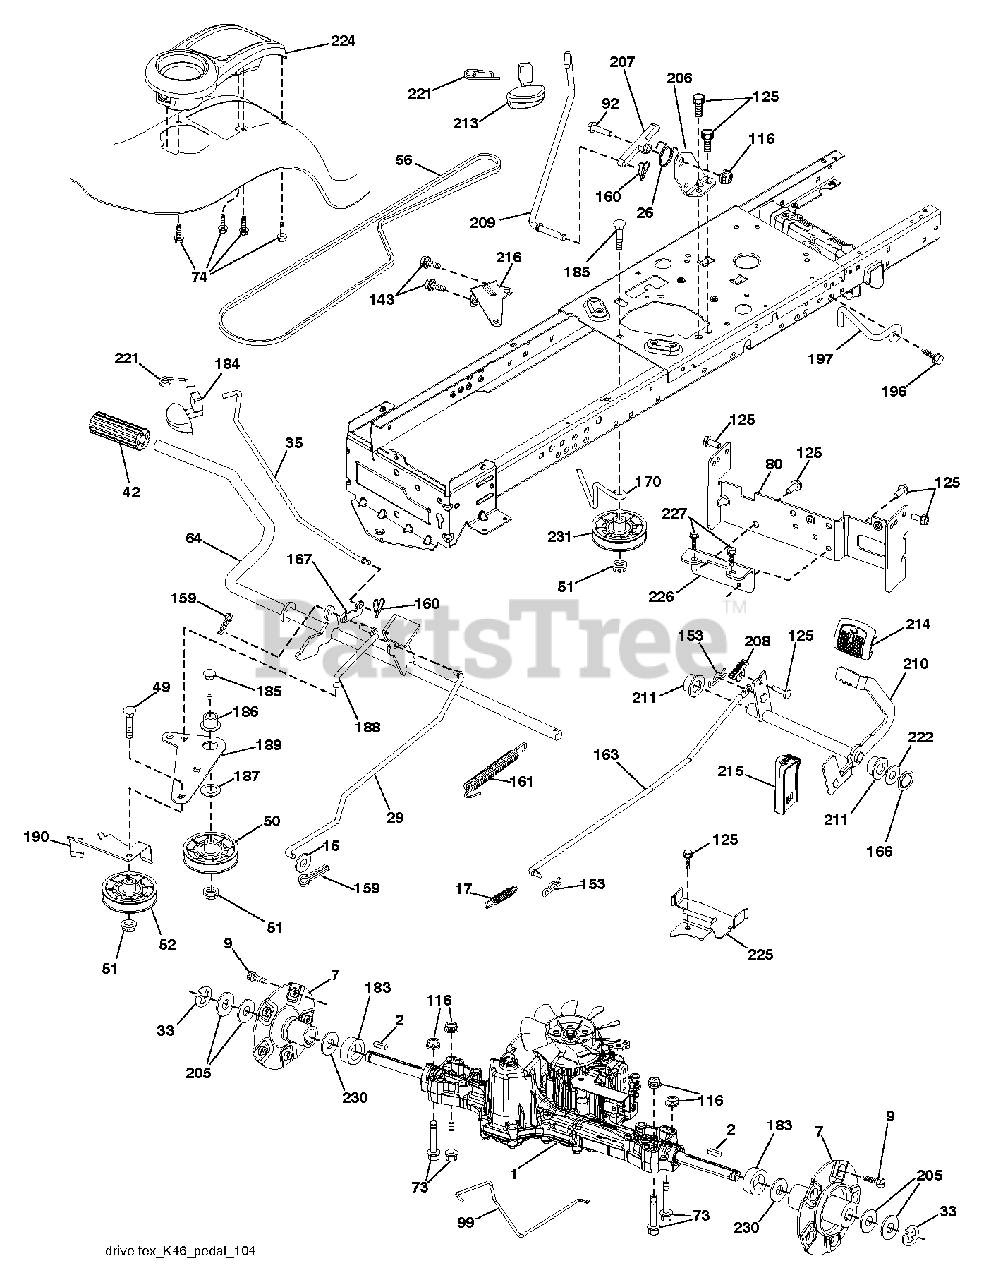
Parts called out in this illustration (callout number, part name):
2	KEY.SQUARE.187X2.500
7	HUB.ASM.WHEEL.REAR.22"
17	SPRING.BRAKE.K46.GREEN
26	SPRING.RETURN.CRUISE
29	ROD.BRAKE.K46
35	ROD.BRAKE.PARTK.HUSQ.TEX
42	PEDAL COVER T
49	BOLT
50	IDLER.FLAT.910.OFFSET
51	NUT LOCK FLG 3/8-16 UNC
52	IDLER.V-GROOVE.910.OFFSET
64	SHAFT.ASM.PEDAL.BRK.CNTR
74	SCREW.HI-LO.CONSOLE
80	STRAP.TORQUE.K46.K57R.TT
92	BOLT
99	ROD.SPRING.BYPASS.K46.LT.Z
116	NUT LOCK HEX FLANGE 5/16-18
125	SCREW
153	RETAINER M
159	COTTER PIN
160	RETAINER CLIP
161	SPRING, RETURN LT
163	ROD.CONTROL.PEDAL.K46
167	LATCH.BRAKE.SPRING
170	KEEPER.CENTER SPAN.1.688
183	SPACER.SPLIT.800X.350
184	HANDLE.PARKG.BRK.HUSQ/PRED.667
186	SPACER.RETAINER
187	WASHER 12/32X2X10GA
188	LINK.CLUTCH.GROUND.DRIVE
189	BELLCRANK.GROUND.DRIVE.TEX.
190	KEEPER.BELLCRANK.DRIVE
196	SCREW 3/8-16X1
197	BRKT.ANIT-ROTATION.CLU
206	BRKT.MOUNT.LATCH.CRUIS
207	LATCH.CONTROL.CRUISE
208	GEAR.SECTOR.CONTROL.CR
209	ROD.CONTROL.CRUISE.GT.
210	ROCKER.ASM.PEDAL.CONTR
211	BEARING.NYLON
213	KNOB.CONTROL.CRUSIE.HU
214	PAD PEDAL FORWARD
215	PEDAL.REVERSE.TEX.GT.4
216	BRACKET.PULLEY.IDLER.W/TEX
221	RETAINER.SPRING.CLIP.H
222	WASHER 21/32 X 1-1/4 X 10 GA.
224	CONSOLE.TOOLBOX.PCH.ERGO.BLACK
225	KEEPER.BELT.TRANSAXLE.K46
226	BRACKET.MOUNT.TORQUE.K46.TLT
227	SCREW
230	WASHER.HARDENED
231	IDLER.V-GROOVE.1.688.OFFSET
